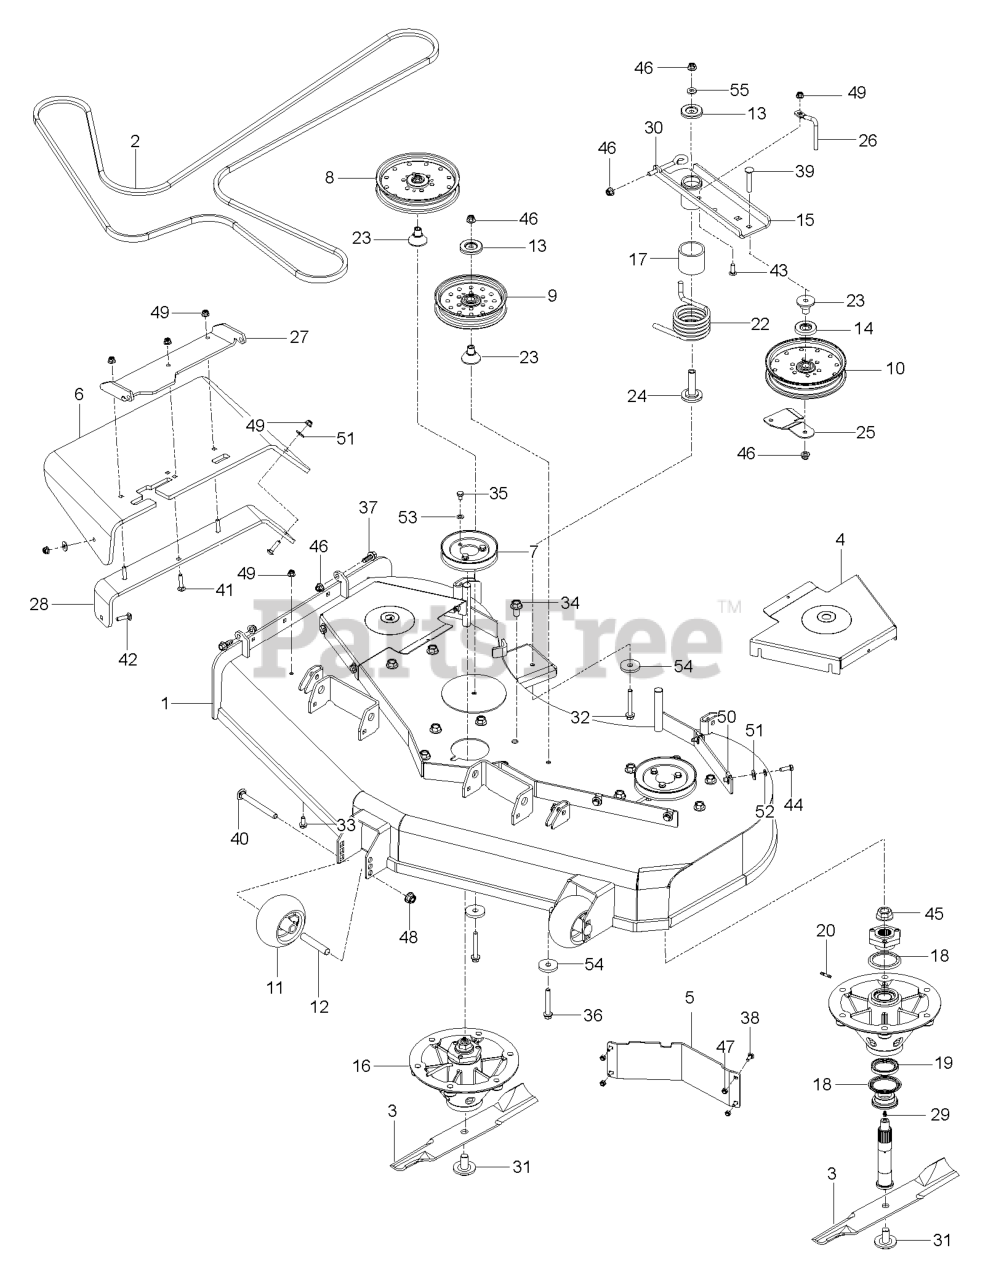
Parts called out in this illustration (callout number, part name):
1	DECK.SHELL.54".FAB.W/DECALS
2	RP_BELT, "5V", 169.75"
3	BLADE 19" HIGH LIFT (3 2)
4	SHIELD,BELT, 60" ORANGE
5	BAFFLE, DIVERTER 54"/60" LH
6	CHUTE, DISCHARGE 48-52
7	PULLEY - 5.93 OVER PINS
8	PULLEY - 7" NARROW
9	PULLEY IDLER, 6" NARROW
10	PULLEY - IDLER 7"
11	ROLLER, GAUGE .635 BORN
12	TUBE, ROLLER AXLE
13	DUST SHIELD
14	SHIELD, DUST
15	IDLER.ARM.BLACK
16	SPINDLE ASM. 10" ALUMINUM
17	SPACER, IDLER PIVOT
18	SEAL V-RING 55MM
19	SEAL SHAFT
20	ADAPTER, FITTING, TUB
22	SPRING, TORSION, IDLER
23	BEARING, IDLER ARM
24	BEARING, IDLER PIVOT
25	BELT.GUIDE.BLACK
26	BELT KEEPER
27	BRKT - CHUTE MTG BLACK
28	BRKT, CHUTE SUPPORT BLACK
30	EYE BOLT, 3/8 X 4"
31	BLADE BOLT/WASHER
32	HCS 3/8-16 X 4-1/2 GR 8 ZD
33	HHFS 5/16-18 X 3/4
34	HHFS 1/2-13 X 1 GR5 ZD
35	HCS 5/16-18 X 1/2 GR 5 ZD
36	HHFS 3/8-16 X 2 3/4
37	HHFS 3/8-16 X 1 GRD 5 ZD
38	1/4-20X3/4 CARR BLT
39	CARRIAGE BOLT 3/8-16 X
40	RHSNB 1/2-13 X 4.75 GR5 ZD
41	RHSNB 5/16-18 X 1-1/2 GR 5 ZD
42	BOLT, CARRIAGE 5/16X1-1/4
43	RHSSNB 5/16C X 1.0
44	HCS 5/16C X 1
45	NUT FLANGE 3/4-16
46	NUT 3/8-16 HEX FLG NYLOC ZD
47	NUT.1/4-20.HEX.NYLOC.ZD
48	NUT, 1/2-13 HEX FLG NYLOC ZD
49	5/16-18 NYLOC FLANGE NUT
50	U-CLIP 5/16-18 NUT RETAINER
51	WASHER 5/16 FLAT
52	WASHER.LOCK.HVY.HLCL.SPR.5/16
53	WASH 5/16 DISC SPRING ZD
54	SPINDLE WASHER
55	WASHER, 3/8 THICK
